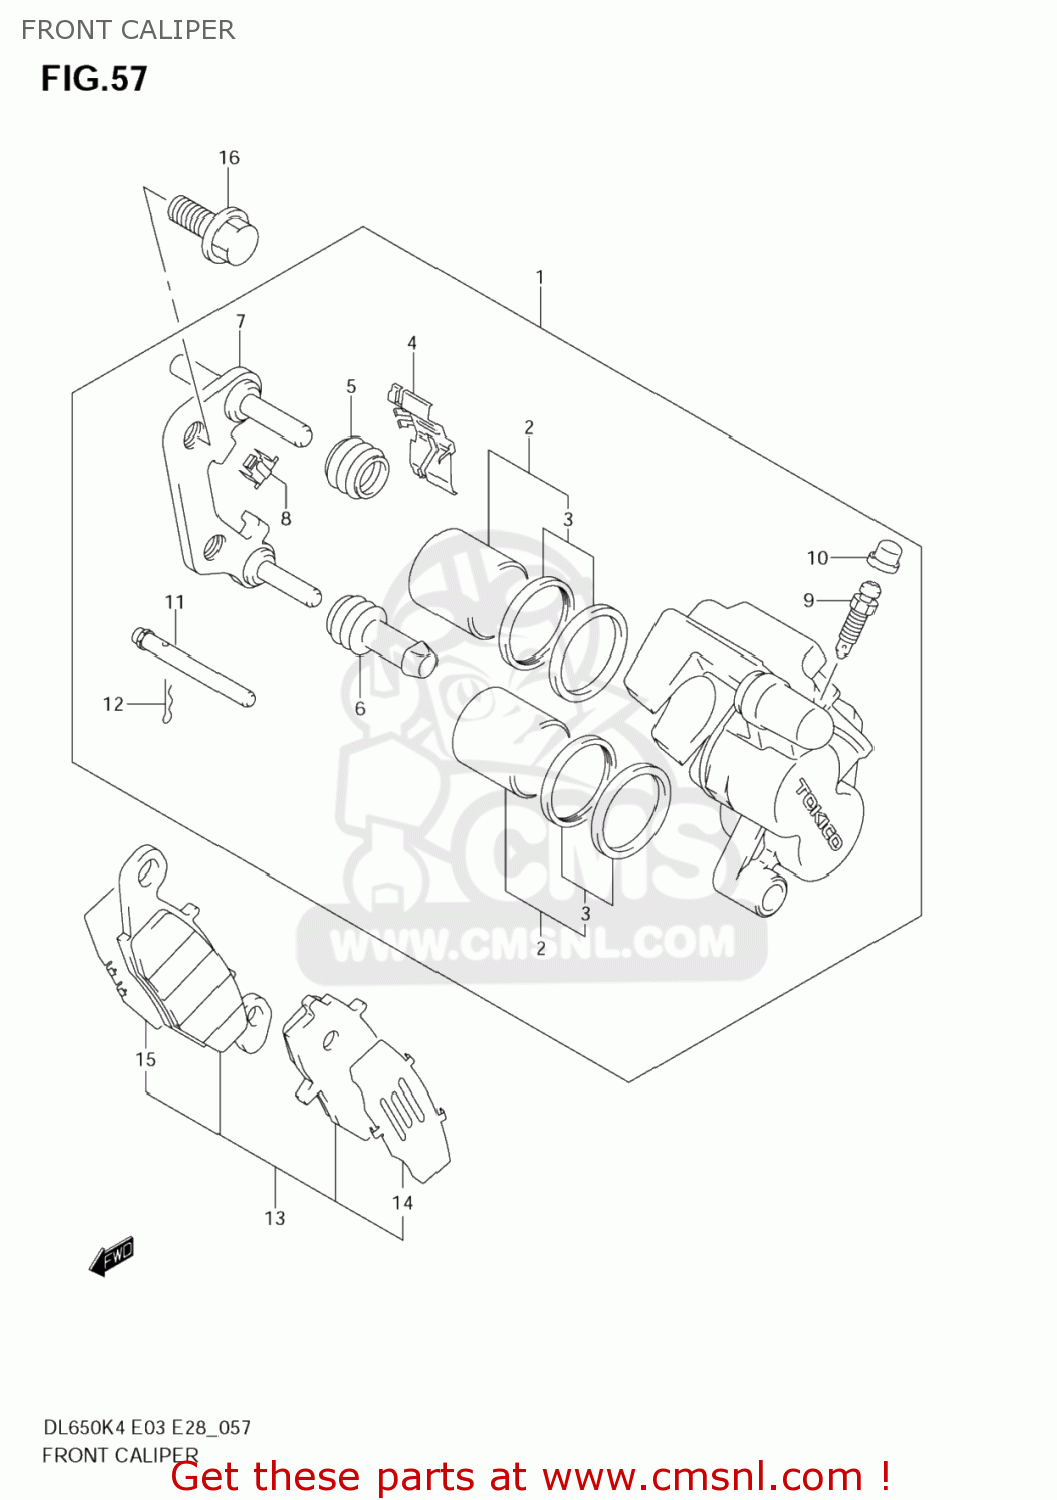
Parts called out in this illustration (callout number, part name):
1	CALIPER ASSY, FRONT RH
2	PISTON SET
3	SEAL SET,PISTON
4	SPRING,PAD,R
5	BOOT,AXLE
6	INSULATOR,AXLE
7	CARRIER,CALIPER,R
8	GUIDE,PAD
9	BLEEDER
10	CAP,BLEEDER PLUG
11	PIN,PAD
12	CLIP,PAD PIN
13	PAD & SHIM SET,R (NAS)
14	SHIM,PAD
15	SHIM,PAD NO.2
16	BOLT(10X25)
